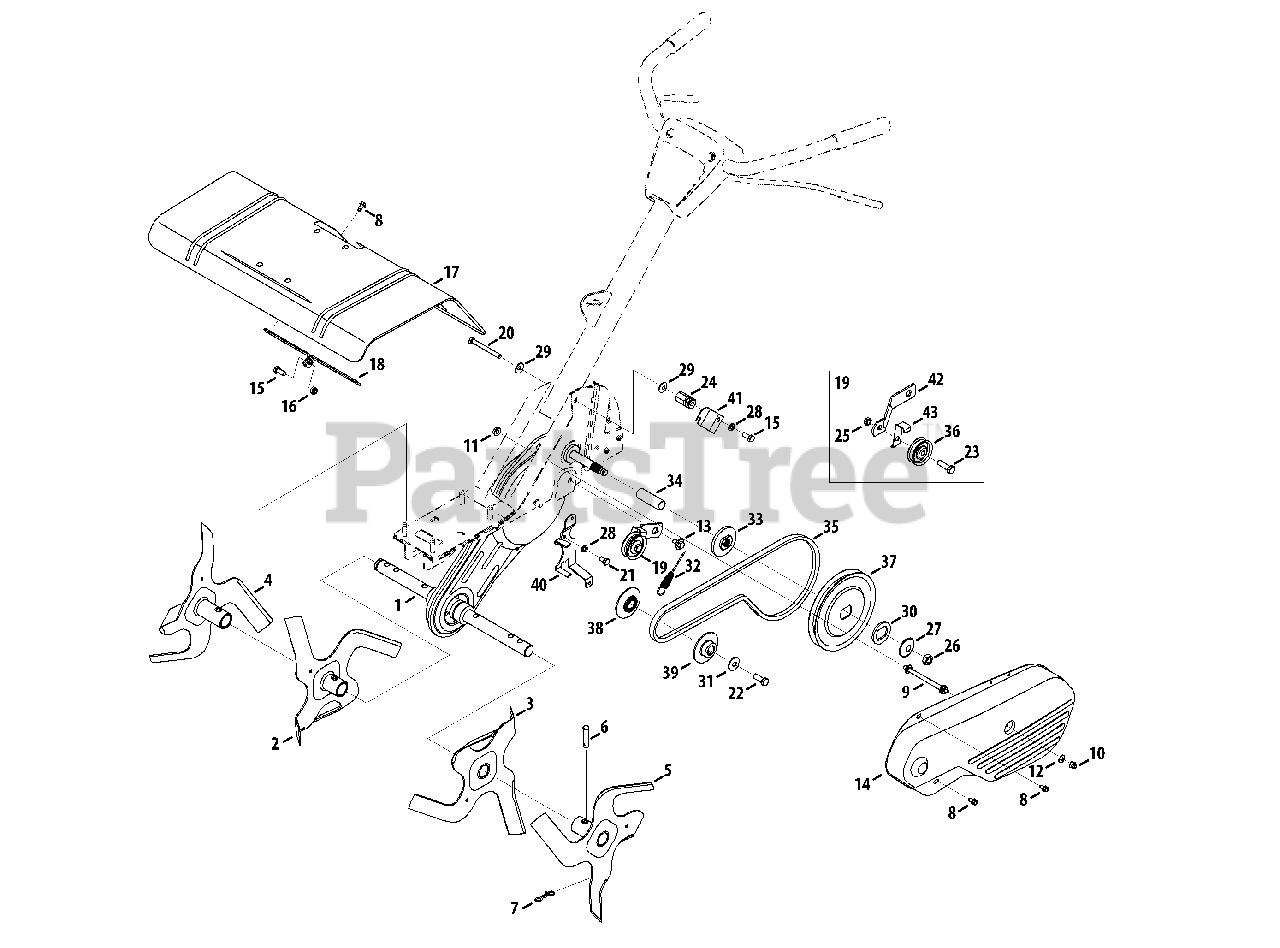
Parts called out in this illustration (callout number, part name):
1	Chain Case Assembly
2	Inner Tine Assembly, RH
3	Inner Tine Assembly, LH
4	Outer Tine Assembly, RH
5	Outer Tine Assembly, LH
6	Clevis Pin, .375 x 1.75
7	Bow Tie Cotter Pin
8	Screw, 1/4-20 x 0.500
9	Bolt, Belt Cover
10	Nut, 1/4-28, Lock
11	Nut, 5/16-18, Flange Lock
12	Flat Washer, .271 x .630 x .065
13	Shoulder Screw, .560 x .165 5/16-18
15	Hex Head Screw, 5/16-18 x .75
16	Nut, 5/16-18, Flange Lock
18	Bracket, Tine Shield
19	Idler Bracket Assembly
20	Hex Head Screw, 5/16-18 x 3.00
21	Hex Head Screw, 5/16-24 x .625
22	Hex Head Screw, 3/8-24 x 1.00
23	Hex Head Screw, 3/8-16 x 1.25
24	Hex Nut, 5/16-18
25	Jamlock Nut, 3/8-16
26	Nut, 1/2-20, Jam
27	Washer, .531 x 1.62 x .045
28	Lock Washer, 5/16
29	Bell Washer, .340 x .872 x .060
30	Flat Washer, 1.26 x 1.87 x .150
31	Bell Washer, .396 x 1.140 x .095
32	Forward Clutch Cable
33	Pulley Adaptor
34	Spacer, .64 ID x 2.4
35	Belt, 4L x 41.9 LG
36	Pulley 1.88 OD
37	Pulley 6.00 OD
38	Inner Engine Pulley
39	Outer Engine Pulley
40	Belt Keeper Bracket
41	Cable Guide Bracket
42	Idler Bracket
43	Belt Keeper
